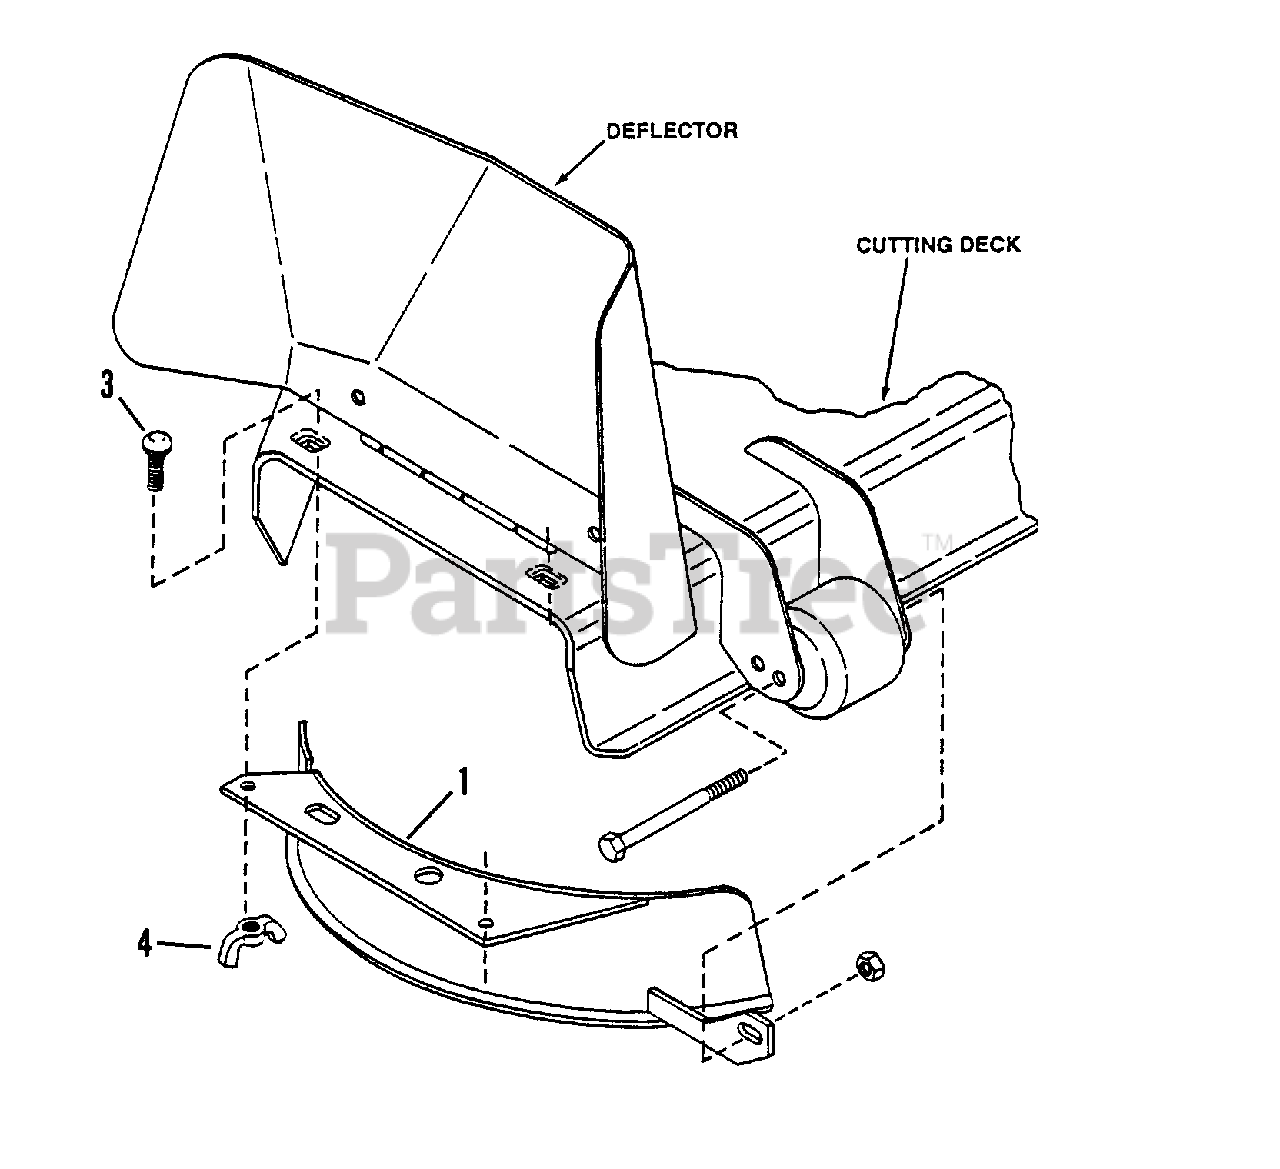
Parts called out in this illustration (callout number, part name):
1	COVER, Recycling
3	BOLT, 5/16-18 x 3/4" Carriage
4	NUT, 5/16-18 Wing Lock YZ
